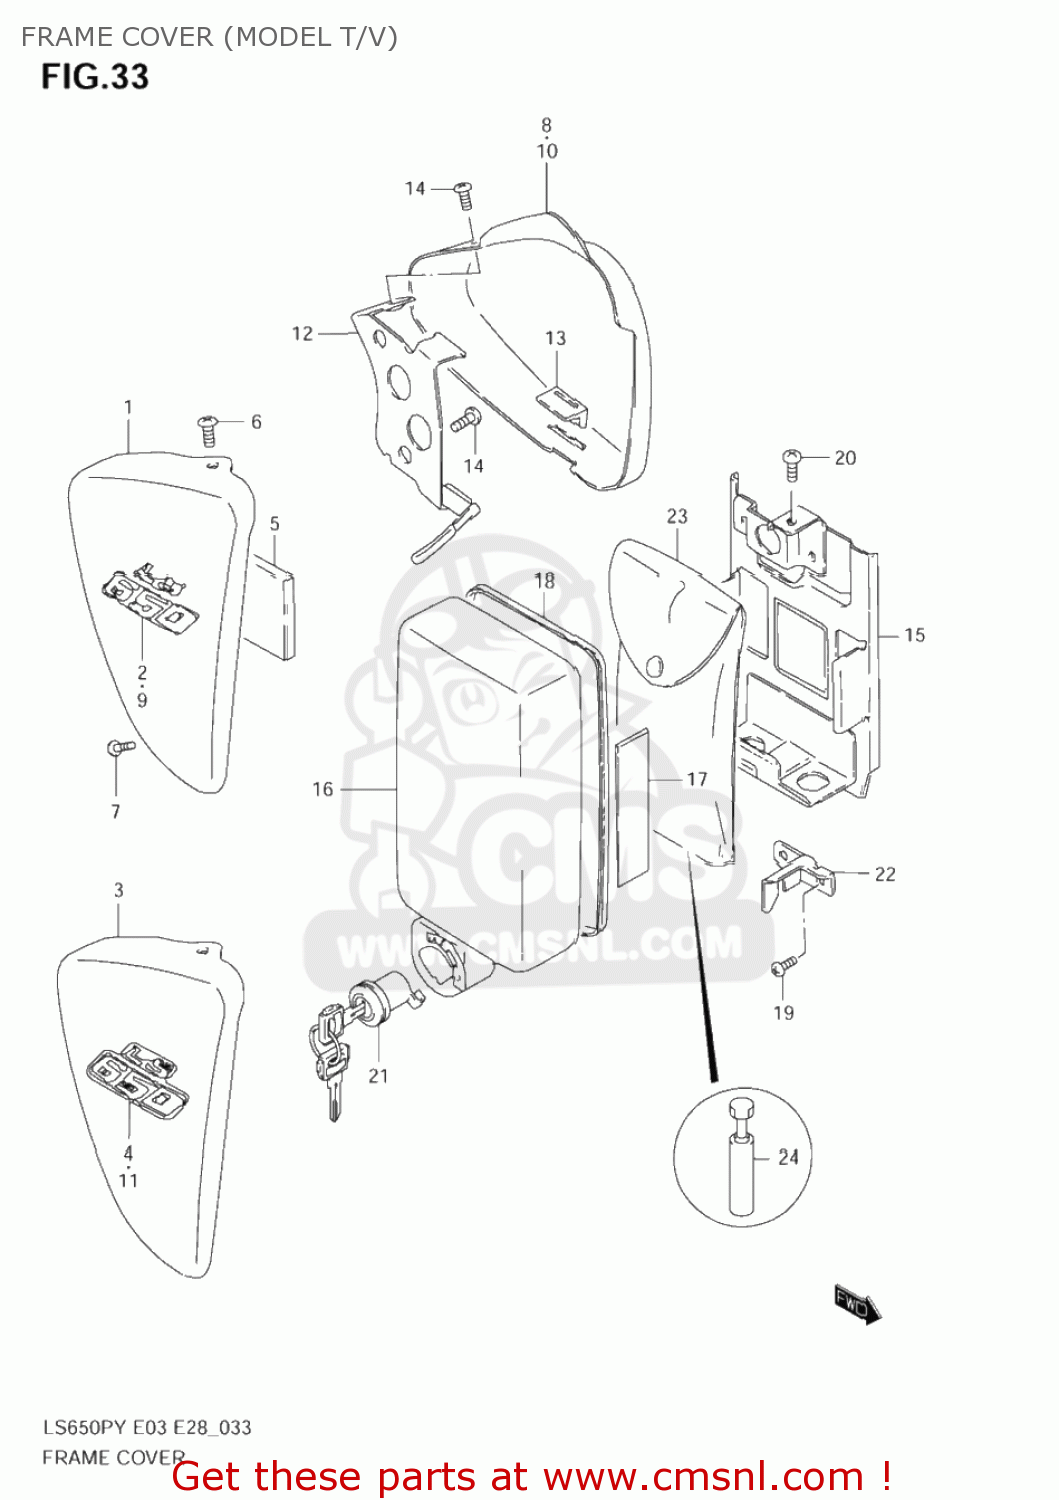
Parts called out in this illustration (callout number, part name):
1	COVER ASSEMBLY,FRAME,RIGHT
2	EMBLEM,FRAME COVER
3	COVER ASSY,FRAME,R(ORANGE)
4	EMBLEM,FRAME COVER
5	PAD
6	SCREW
7	SCREW
8	COVER ASSEMBLY,FRAME,LEFT
9	EMBLEM,FRAME COVER
10	COVER ASSEMBLY,FRAME,LEFT (BLACK)
11	EMBLEM,FRAME COVER
12	BRACKET,FRAME COVER,L
13	CUSHION,FRAME COVER
14	SCREW
15	HOLDER,TOOL
16	COVER COMP,TOOL HOLDER
17	PROTECTOR(80X80X2)
18	MOLDING
19	SCREW
20	SCREW
21	LOCK SET,TOOL HOLDER
22	PLATE,TOOL HOLDER LOCK
23	TOOL ASSY
24	GAUGE ASSY,TENSION
